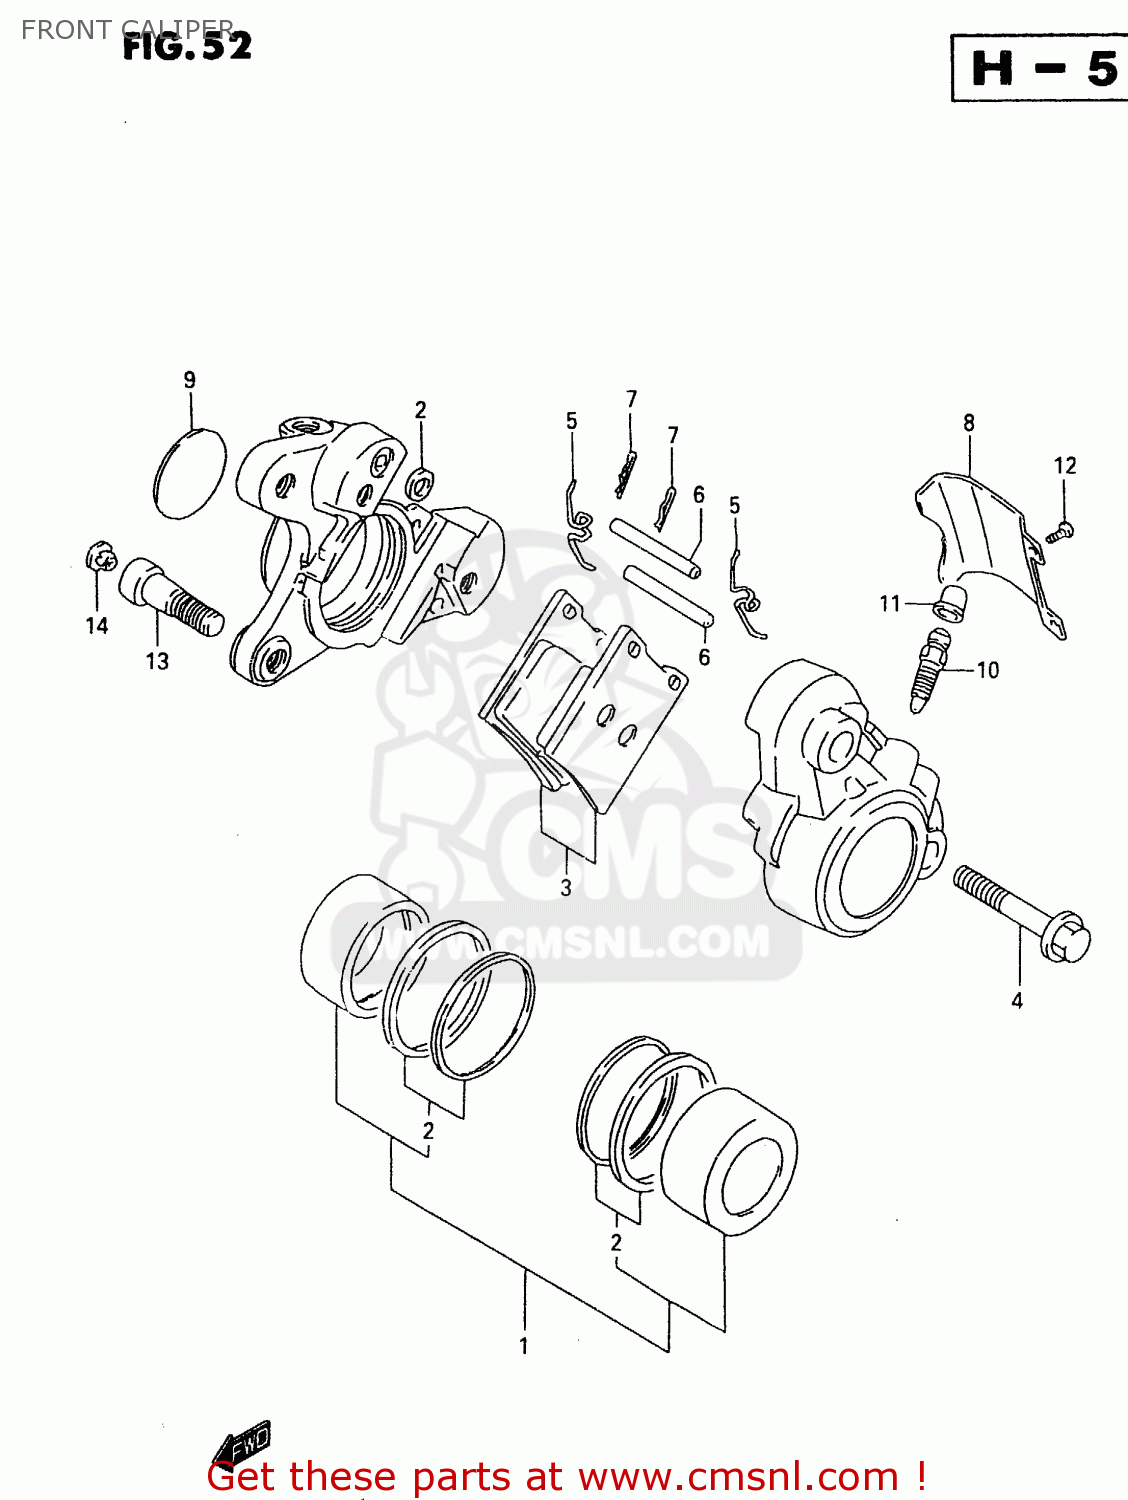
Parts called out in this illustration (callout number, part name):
1	PISTON SET
2	SEAL SET,PISTON
3	PAD SET (NAS)
4	BOLT,HOUSING
5	SPRING
6	PIN,PAD
7	CLIP,PAD PIN
8	COVER,CALIPER HOUSING,DUST
9	CAP,CALIPER
10	BLEEDER
11	CAP,BLEEDER PLUG
12	SCREW,CALIPER COVER(4X6)
13	BOLT(10X33)
14	CAP(OD:12)
